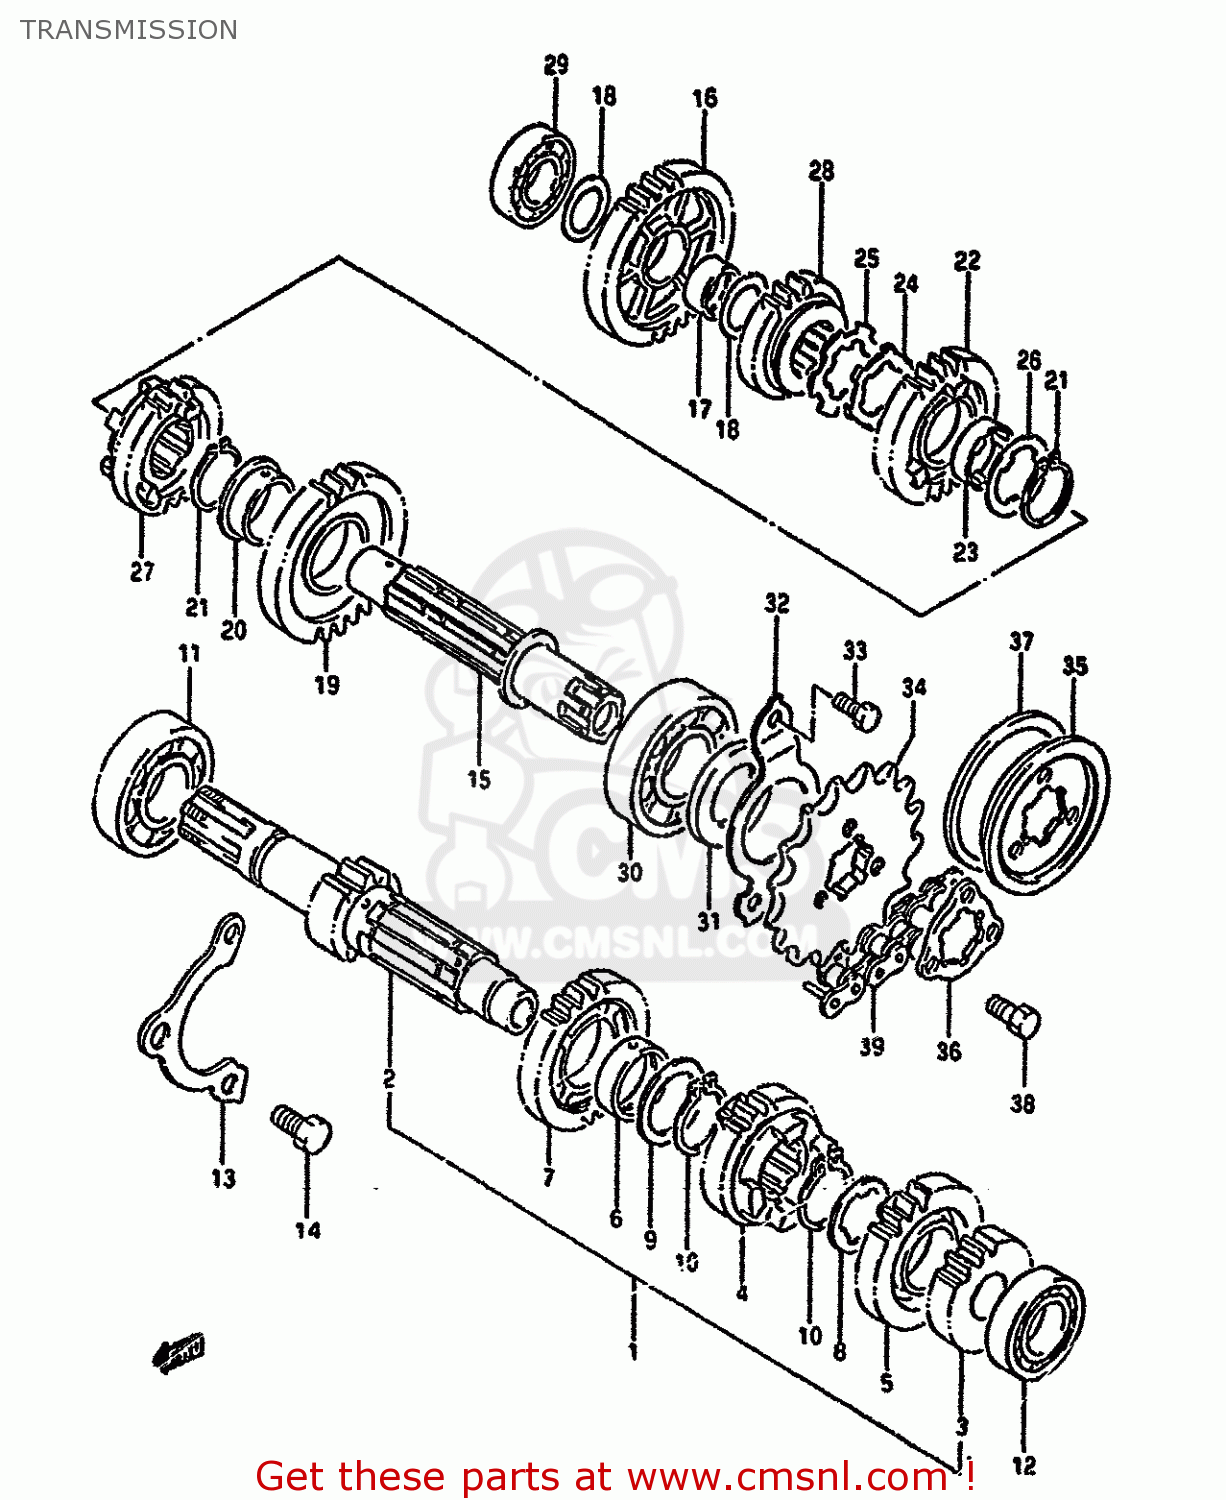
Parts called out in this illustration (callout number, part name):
1	SHAFT,COUNTER
2	SHAFT,COUNTER
3	GEAR,SECOND DRIVE
4	GEAR,3RD DRIVE
5	GEAR,FOURTH DRIVE
6	BUSHING 25X29X10
7	GEAR,5TH DRIVE
8	WASHER,LOCK
9	WASHER
10	RING,SNAP
11	BEARING
12	BEARING
13	RETAINER,CNTR SHAFT BEARING
14	BOLT
15	SHAFT,DRIVE
16	GEAR,1ST DRIVEN
17	BUSH(20X24X13)
18	WASHER
19	GEAR,2ND DRIVEN
20	BUSH
21	RING,SNAP
22	GEAR,3RD DRIVEN
23	BUSHING
24	WASHER
25	WASHER,LOCK
26	WASHER,LOCK
27	GEAR,FOURTH DRIVEN
28	GEAR,FIFTH DRIVEN
29	BEARING(20X42X12)
30	BEARING(25X62X17)
31	SEAL,OIL(25X45X5)
32	RETAINER,DRIVE SHAFT OIL SEAL
33	BOLT
34	SPROCKET,ENGINE(NT:16)
35	PLATE,ENGINE SPROCKET
36	PLATE,ENGINE SPROCKET
37	DAMPER,ENGIN SPROCKET
38	BOLT(6X13)
39	CHAIN ASSEMBLY,DRIVE
